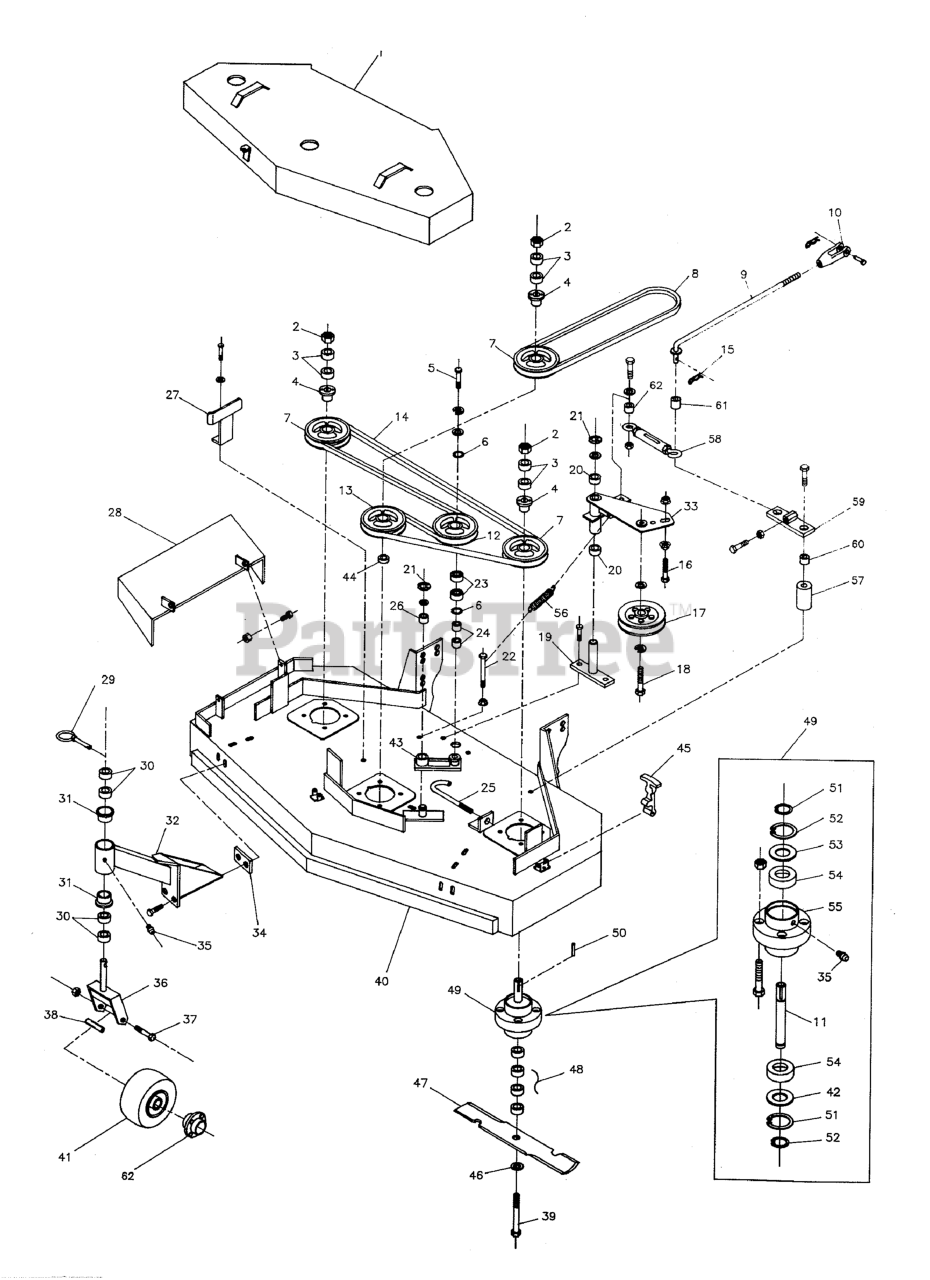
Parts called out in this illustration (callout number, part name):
1	48" Guard
2	NUT, 5/8-11 Hex
3	SPACER, .63 x 1.06 x .23
4	BUSHING, Tapered Hub
5	BOLT, 1/2-20 X 1-3/4" GD8 CZ
6	SNAP RING, Internal
7	PULLEY, Spindle
9	Belt Engagement Rod
10	CLEVIS, 3/8-24, Plastic
11	SPINDLE SHAFT
12	PULLEY, Idler
13	SPINDLE PULLEY
14	BELT, Blade Spindle
15	HAIRPIN CLIP
16	BOLT, 5/16-18 x 1-3/4
17	Idler Pulley
18	BOLT, 1/2-20 X 1-1/2, GD5 CZ
19	Idler Mount
20	BUSHING, Brass
21	C-CLIP
22	BOLT, 5/16-18 x 3
23	BEARING, BALL 11/16X1-9/16X15/32
24	INSERT, Bearing
26	BUSHING, Brass
27	Belt Guide
28	CHUTE, DISCHARGE WELDMENT
29	PIN, Lynch
30	SPACER, 1.02 x 1.56 x .50
31	BUSHING, Flange
32	Caster Support
33	Blade Engagement Pivot
34	Caster Mount Spacer
35	GREASE FITTING
36	YOKE, Caster
37	BOLT, 1/2-13 x 5-1/2
38	AXLE, Caster Wheel
39	BOLT, 5/8-11 x 9-1/2
40	48" MOWER HOUSING
41	WHEEL & TIRE ASSEMBLY, White, 9 x 3.5 x 4, Complete
41	TIRE, Front, 9 x 3.5 x 4
41	HUB & BEARING ASSEMBLY, Complete, White
42	SPINDLE WASHER, Bottom
43	IDLER ARM
44	SPACER, 1.00 X 1.25 X .25
45	RUBBER LATCH
46	WASHER, 5/8" USS
47	MOWER BLADE, 16-1/4"
48	SPACER, .63 x 1.06 x .23
49	SPINDLE ASSEMBLY, Complete
50	KEY, 1/4 SQ. X 2-1/2
51	SNAP RING, External
52	SNAP RING, Internal
53	SPINDLE WASHER, Top
54	BEARING
55	SPINDLE HOUSING
56	SPRING, Extension
57	SPACER, .39 x 1.00 x 1.75
58	TURNBUCKLE ASSY
59	Blade Linkage Bracket
60	SPACER, .38 x .50 x .27
61	SLEEVE
62	HUB & BEARING ASSEMBLY, Complete, White
